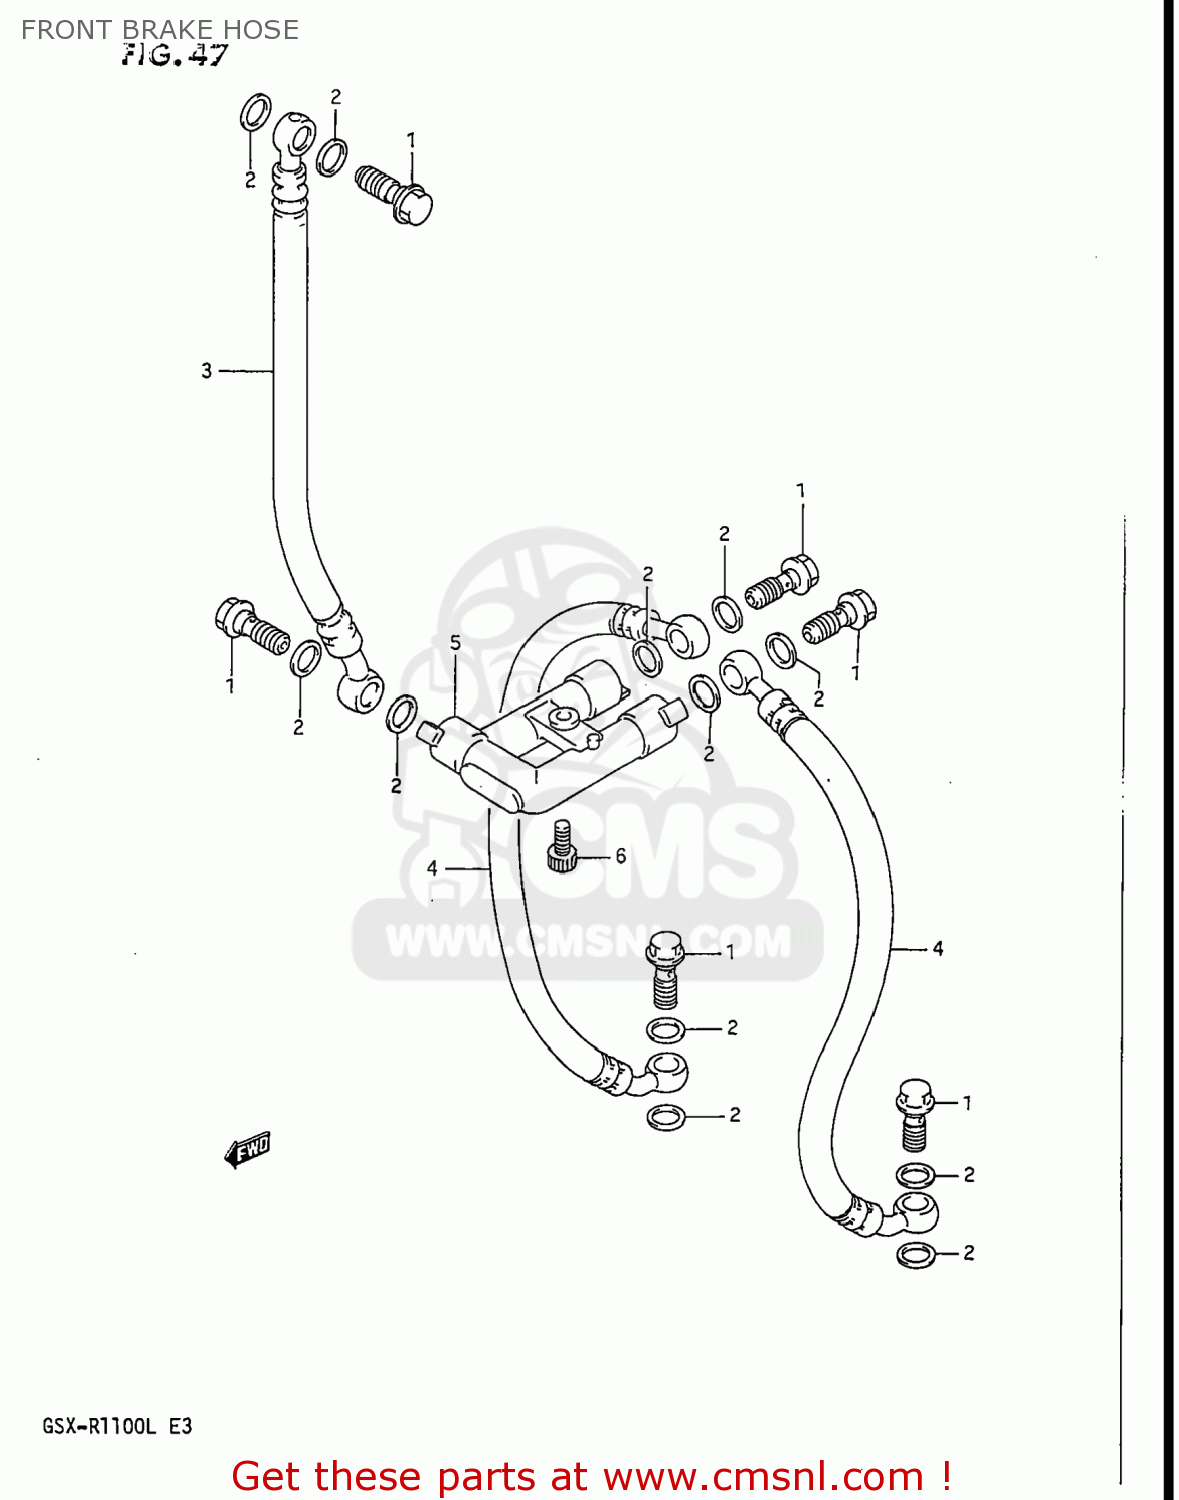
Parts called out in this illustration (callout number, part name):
1	BOLT UNION
2	WASHER(10X15X1.5)
3	HOSE,FRONT BRAKE
4	HOSE,FRONT BRAKE
5	JOINT,BRAKE HOSE
6	BOLT
